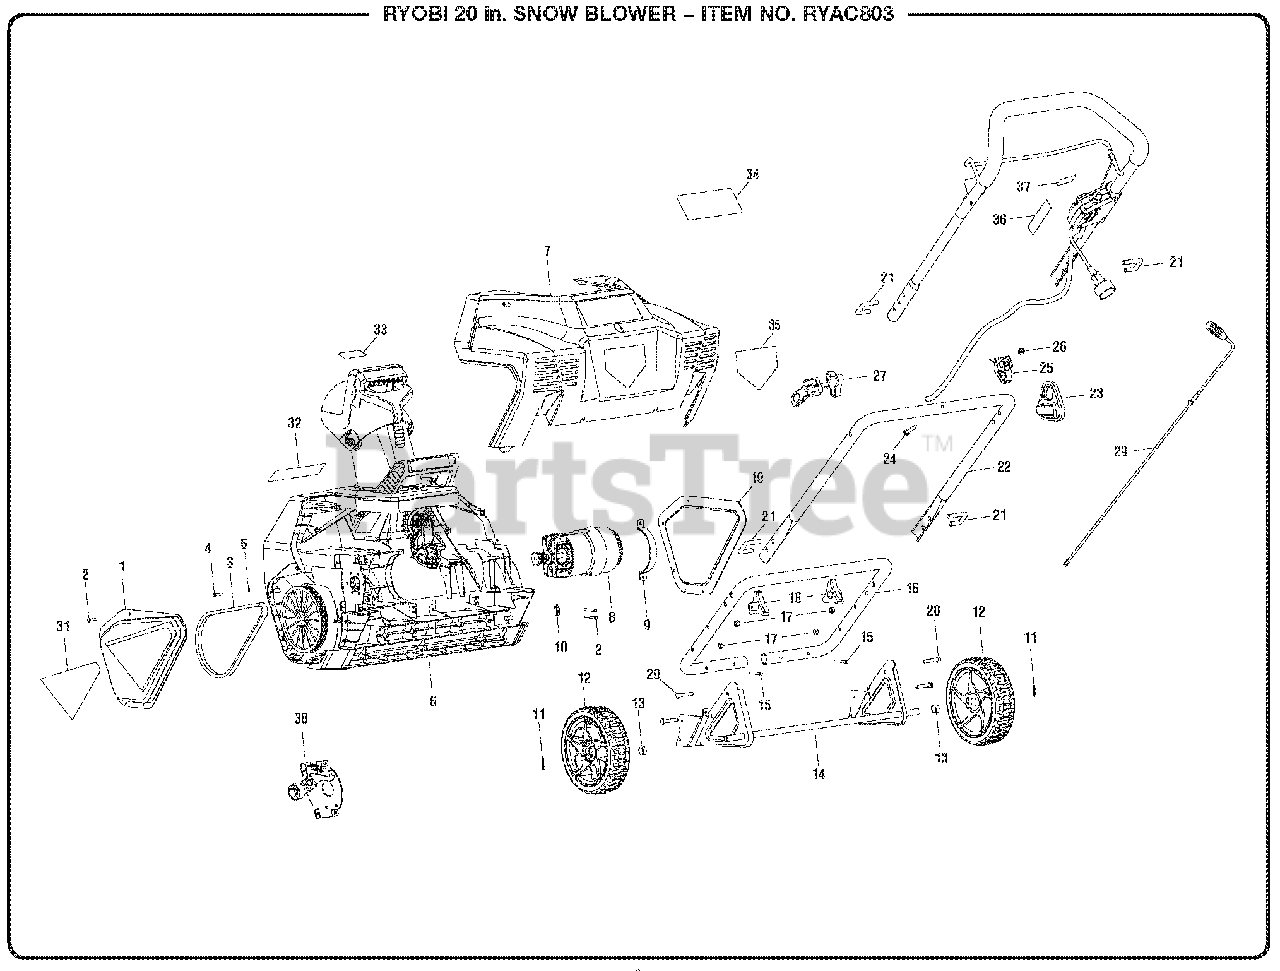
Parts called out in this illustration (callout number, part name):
1	Left Side Cover
6	Front Housing
7	Back Housing
8	Motor
9	Motor Bracket
16	Lower Handle Assembly
19	Right Side Cover
22	Middle Handle Assembly
23	Cord Retainer
25	Lever Bracket
28	Upper Handle Assembly
29	Chute Adjustment Lever
30	Belt Tensioner Assembly
31	Logo Label
32	Front Logo Label
33	Chute Icon Label
34	Data Label
35	Danger Label, No Hands/Feet
36	Start Label
37	Handle Logo Label
